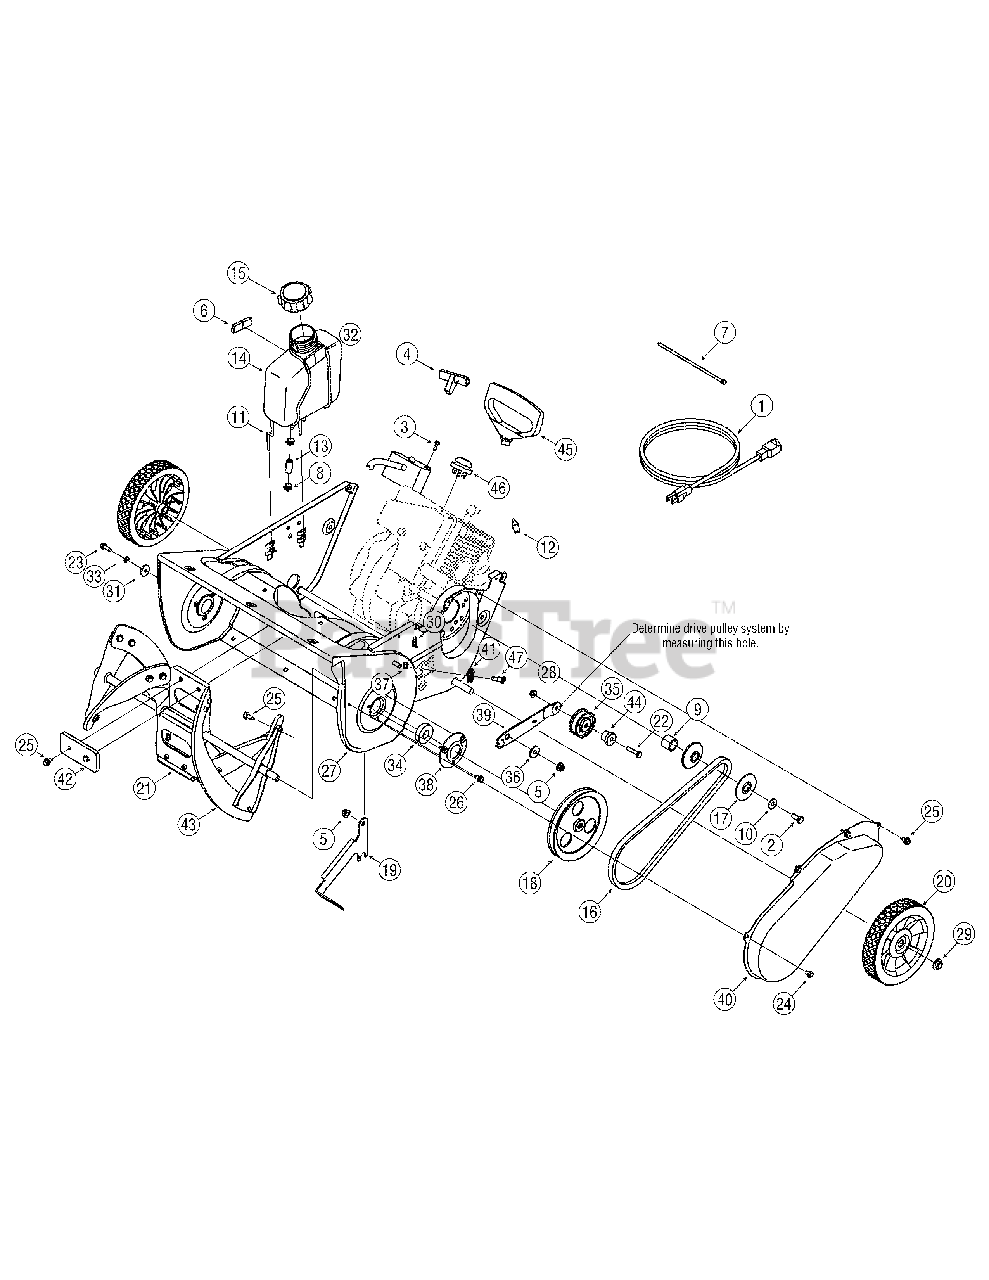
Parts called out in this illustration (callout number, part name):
1	Extension Cord
2	Hex Screw, 5/16-24 x .75
3	Screw, #10-16 x .625
4	Recoil Handle
5	Hex Flange Lock Nut, 5/16-18
6	Foam Tape .625 X.25
7	Push Mount Cable Tie
8	Clamp, Hose
9	Spcr., .630 x .880 x .747
10	Bell Washer, .340 x .872 x .060
11	Gas Tank Support Wire
12	Choke Lever Knob
13	Hose, Fuel Line
14	Tank, Fuel
15	Cap, Fuel
16	V-Belt, 3/8 x 34.4 Lg.
17	Pulley Half, .625 ID x 2.25 OD
18	Pulley, V Type, 3/8 x 6.0 OD
19	2-Cycle Mounting Bracket
20	Wheel, 7 x 1.5 Dia. Tread
21	Auger Assembly Complete
22	Hex Screw, 1/4-20 x 1.00 Gr. 5
22	Hex Screw 3/8-24 x 1.25
23	Hex Screw 1/4-20 x .75 Gr. 5
24	Self-tapping Screw 1/4-20 x .375
25	Hex Screw, 1/4-14 x 0.625"
26	Screw, 1/4-14 x .375
28	Hex Flange Lock Nut, 1/4-20
28	Jam Lock Nut 3/8--24
29	Push Cap, 1/2"
30	Extension Spring
31	Flat Washer .265 x .938 x .120
32	Fuel Tank Gasket
33	Lock Washer, 1/4
34	Ball Bearing
35	Idler Pulley
36	Shoulder Spacer .25
37	Hex Lock Nut 1/4-28
38	Bearing Cup
39	Idler Brkt. w/Brake
39	Idler Brkt. w/ Brake
41	Cable Roller
42	Rubber Paddle
43	Crescent Spiral
44	Shldr., Spcr., .260 x .785 x .538
45	Recoil Handle, Mitten
47	Carriage Screw 1/4-28
